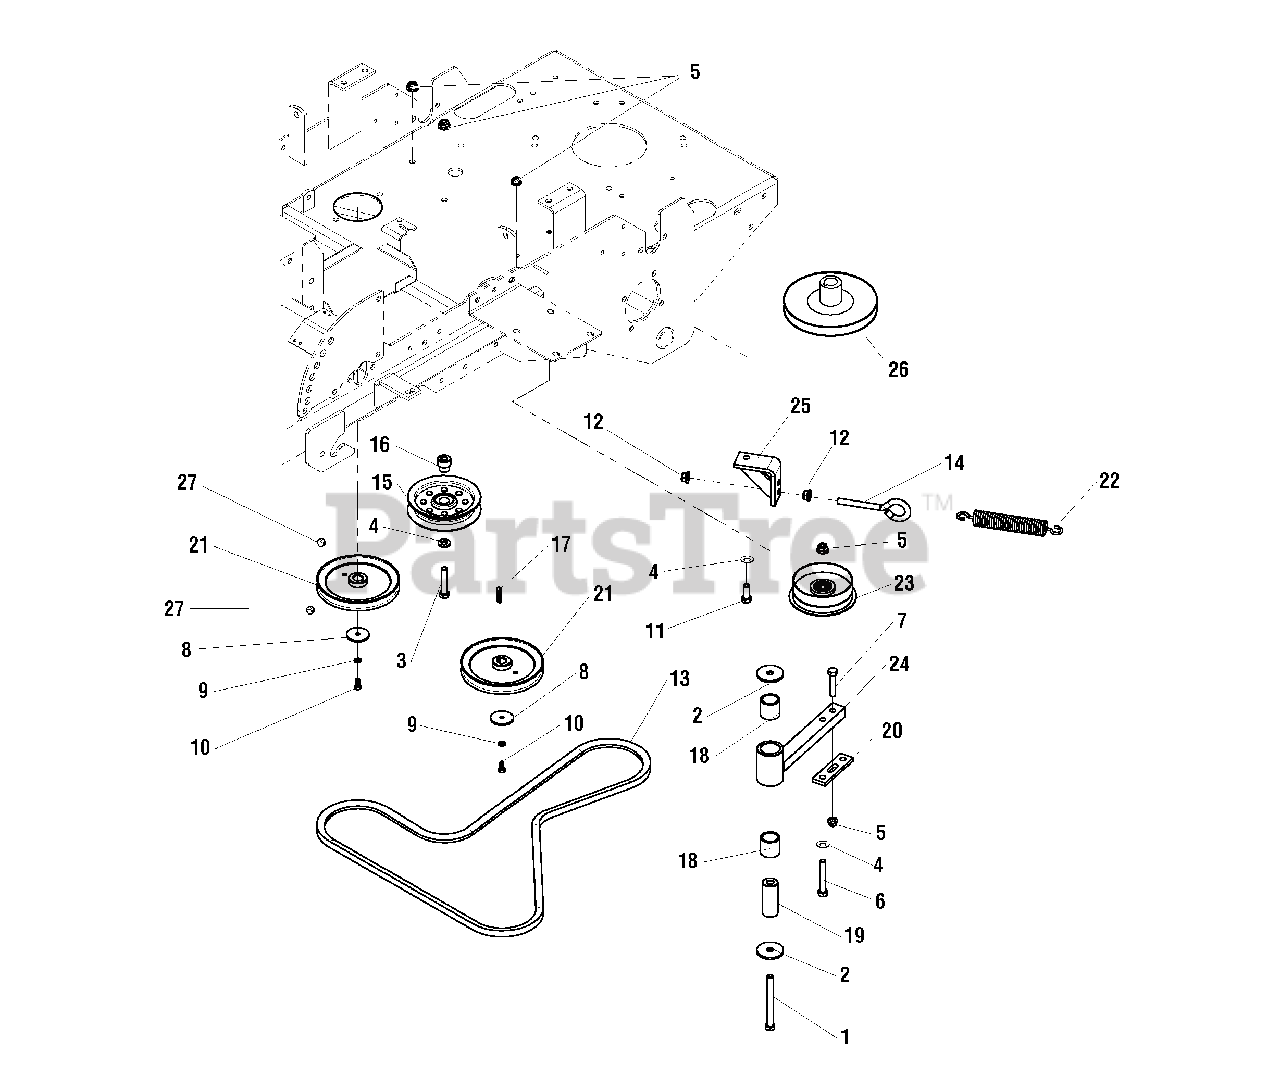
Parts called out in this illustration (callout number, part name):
1	BOLT, 3/8-16 X 4" GD5
2	WASHER, .41 X 1.75 X .14
3	BOLT, 3/8-16 X 2" GD5
4	WASHER, 3/8 SAE
5	NUT, 3/8-16 HEX NYLOCK FLANGE
6	BOLT, 3/8-16 X 2-1/2" GD5
7	BOLT, 3/8-16 X 1-3/4" GD5
8	WASHER, .265 X 1.50 X .109, YZ
9	WASHER, 1/4" LOCK
10	BOLT, M6-1.0 X 14MM
11	BOLT, 3/8-16 X 1" GD5
12	NUT, 3/8-16 HEX
13	BELT, DECK DRIVE
14	EYE BOLT, 3/8-16 X 5", 1" EYE
15	PULLEY, IDLER
16	SPACER, HYDRO IDLER PULLEY
17	KEY, 5MM SQ W/ RADIUS
18	BUSHING, BRASS, 1.25 X 1 X 1.25
19	SPACER, .39 X 1.00 X 2.55, SS
20	PLATE, ANCHOR, SPRING
21	PULLEY, PUMP DRIVE
22	SPRING, EXTENSION, 1.00
23	PULLEY, IDLER, SINGLE FLANGE
24	WELD, ARM, PUMP DRIVE IDLER - BLK
25	WELD, ANCHOR EYEBOLT
26	PULLEY, Crankshaft
27	SET SCREW, 5/16-18 X 1/2
